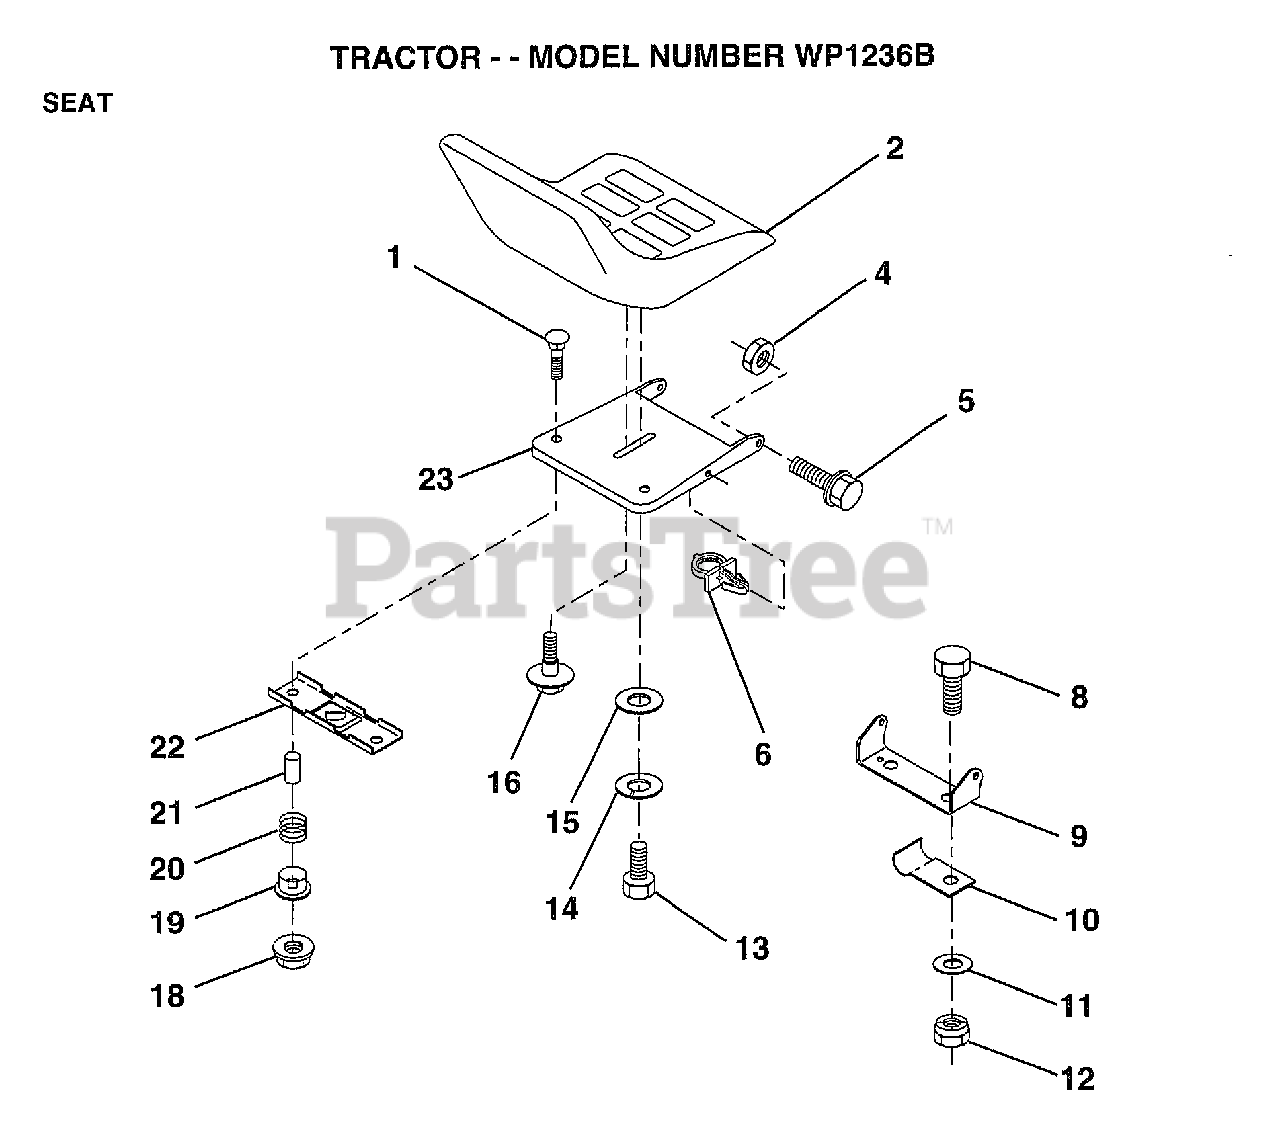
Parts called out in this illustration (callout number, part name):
4	NUT
5	BOLT.SHLD.5/16-18
6	CLIP.PUSH-IN.HING
8	BOLT
9	BRACKET PVT SEAT
10	"CLIP,INSULATOR"
11	WASHER
12	NUT
13	BOLT
14	LOCKWASHER
15	WASHER
16	"BOLT,SHOULDER"
19	BUSHING
20	SPRING
21	SPLIT SPACER
22	BRKT SWITCH
